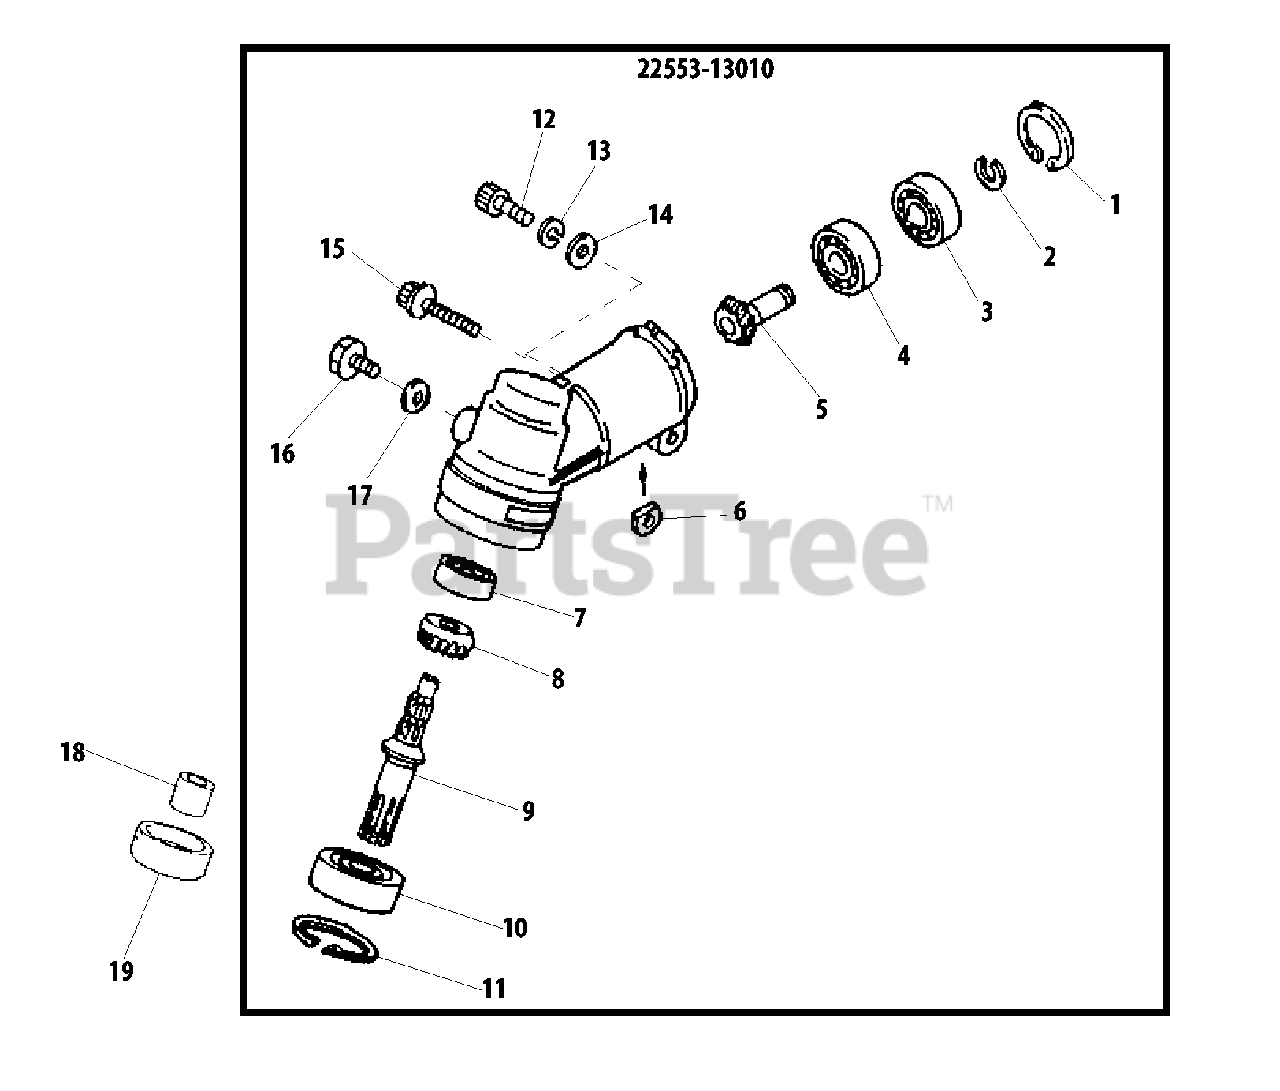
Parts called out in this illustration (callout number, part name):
1	RING, SNAP Ø22
2	RING, SNAP
3	BEARING, BALL 608ZZ
4	BEARING, BALL 608
5	PINION
6	D-WASHER
7	BEARING, BALL 626
8	GEAR, BEVEL
9	SHAFT, GEAR
10	BEARING, BALL 6000DDU
11	RING, SNAP Ø26
12	BOLT 5×12
13	WASHER, SPRING 5
14	WASHER, FLAT 5.5×10×0.8
15	BOLT M5×25
16	BOLT M6×10
17	WASHER
18	COLLAR
19	HOLDER
22553-13010	GEAR CASE ASSY
